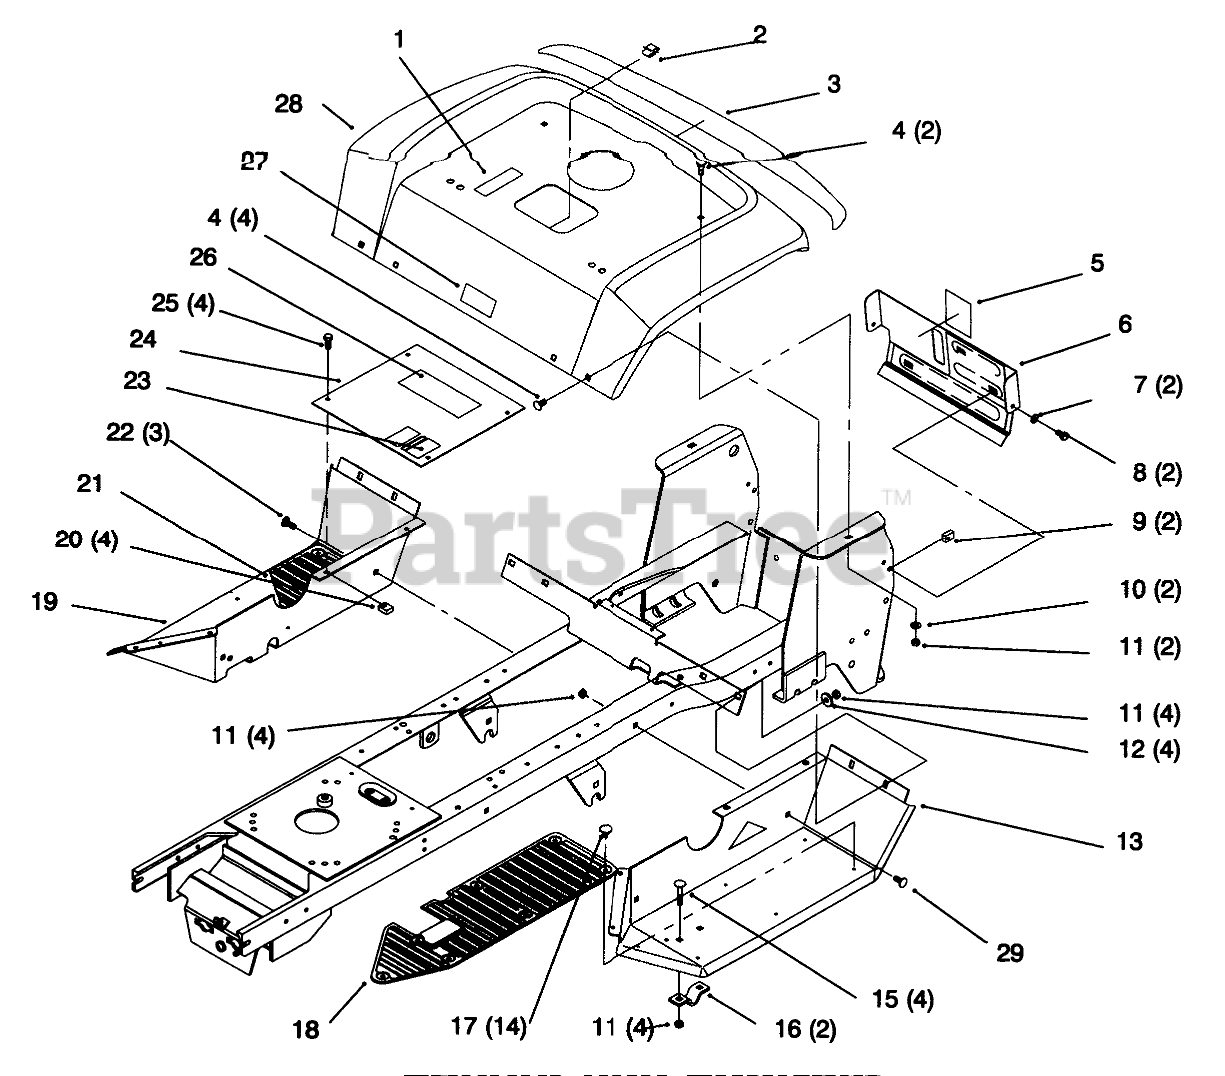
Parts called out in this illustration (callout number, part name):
1	Decal-Model/Serial
2	CLIP-RETAINER, WIRE
3	DECAL - REAR FENDER
4	BOLT-CARR
5	DECAL-LEVEL, FUEL
6	WA- REAR COVER (BLACK)
7	WASHER-FLAT
8	SCREW-HH
9	NUT-SPEED
10	WASHER-PLAIN
11	NUT-LOCK, NI
12	WASHER
13	FOOTREST-LH
15	SCREW-CARR
16	CLAMP
17	FASTENER-PANEL
18	FOOTPAD-LH
19	FOOTREST-RH
21	FOOTPAD-RH
22	SCREW-CARR
23	Decal-HOC (Only On: 72046)
23	Decal-HOC (Only On: 72064)
24	Plate-Footrest W/Decal (Only On: 72046)
24	Plate-Footrest W/Decal (Only On: 72064)
25	SCREW-HH
26	Decal-Danger (Only On: 72046)
26	Decal-Danger (Only On: 72064)
27	Decal-USA (Only On: 72046)
29	SCREW-CARR
